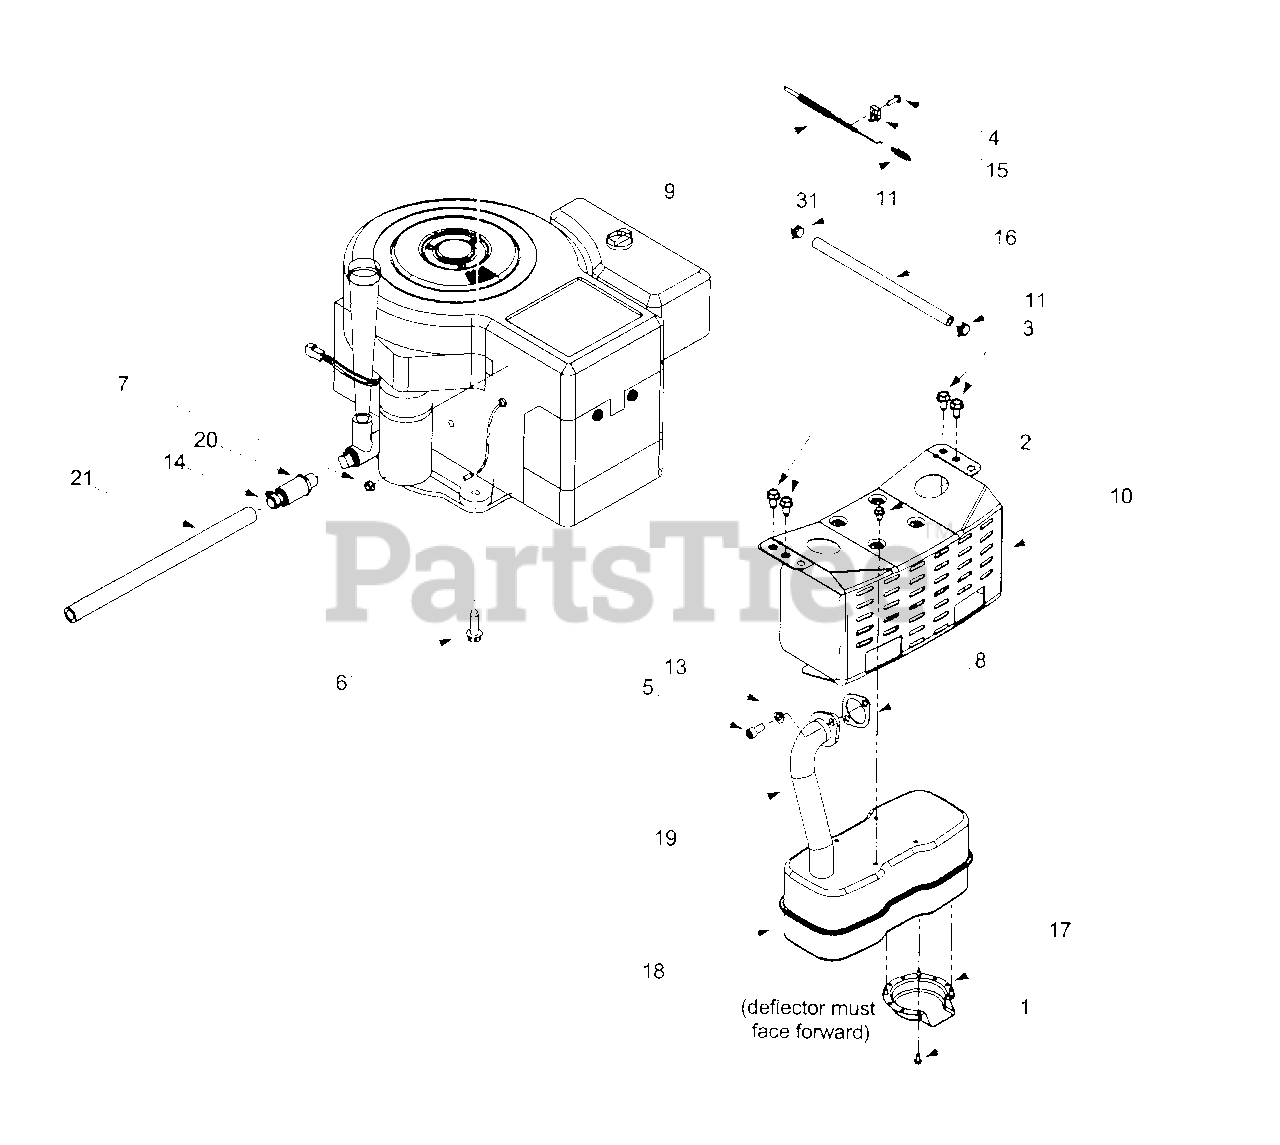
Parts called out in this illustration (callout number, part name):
1	Self-tapping Screw, #8-18 x .5
2	Self-tapping Screw, 1/4-20 x .5
3	Self-tapping Screw, 5/16-18 x .625
4	Screw, #10-32 x .625
5	Socket Cap Screw, 5/16-18 x .625
6	Self-tapping Screw, 3/8-16 x 1.25
7	Sems Nut, 1/4-20
8	Exhaust Gasket
9	Throttle Cable
13	Lock Washer, 5/16
14	Oil Drain Cap
15	Casing Clamp
16	Fuel Line Hose
17	Muffler Deflector
18	Muffler
19	Exhaust Pipe
20	Oil Drain Valve
21	Oil Drain Hose
